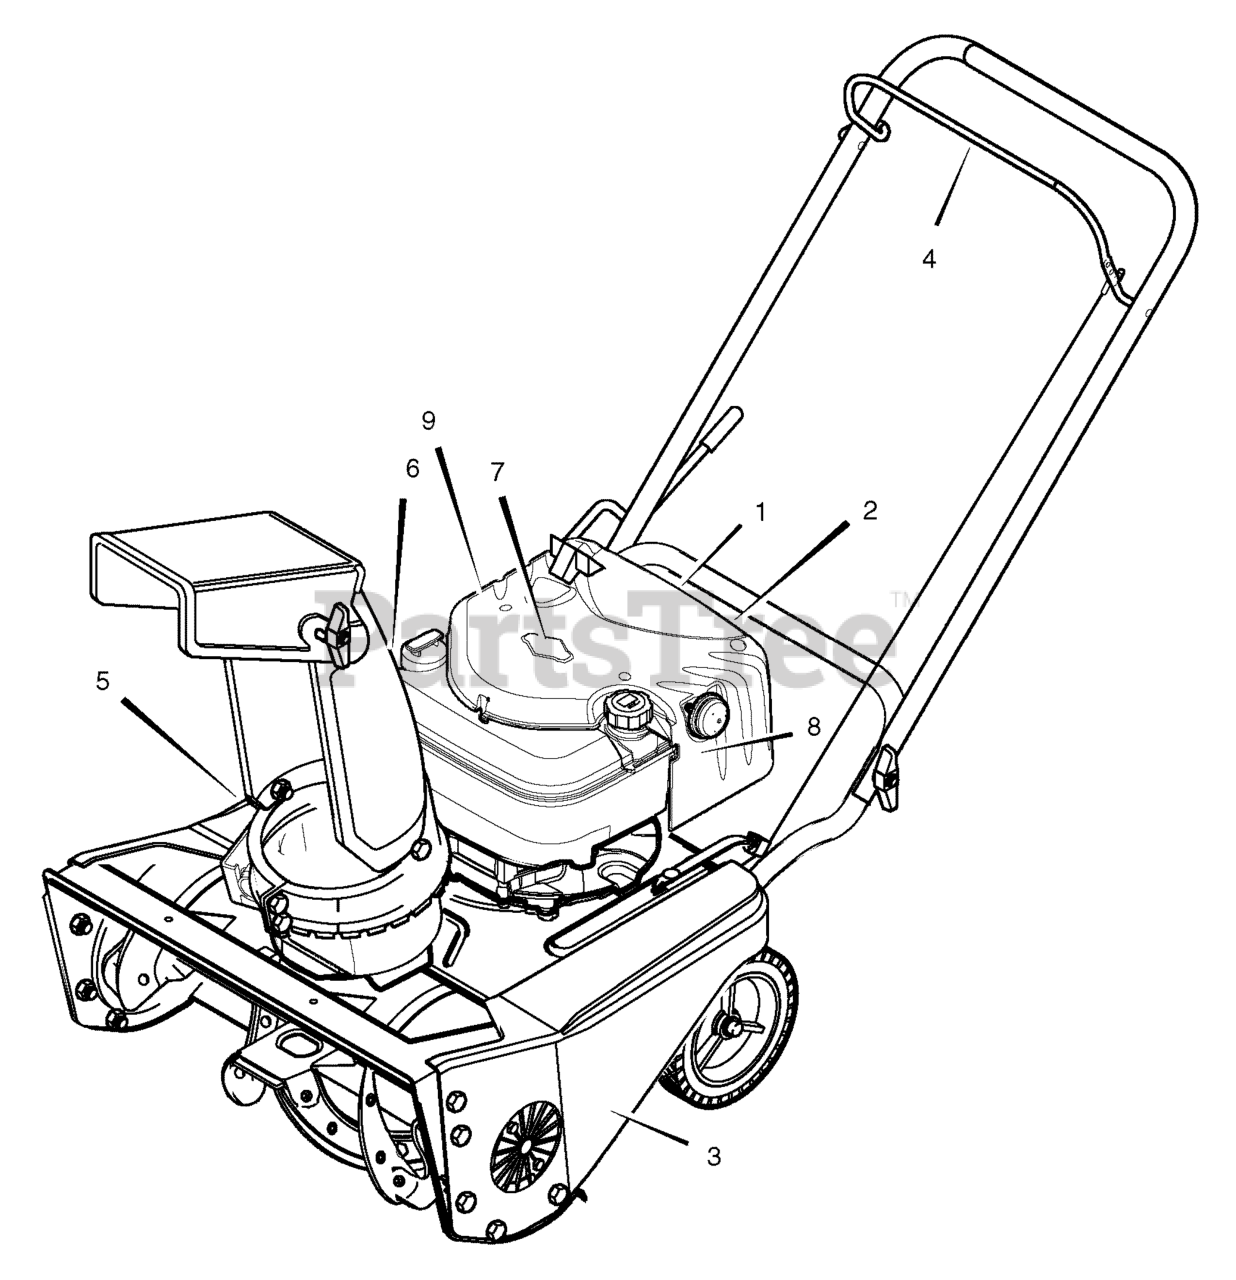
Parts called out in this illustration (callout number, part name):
1	Decal, 650/cm
2	Decal, Choke
3	Decal, Belt Instruction (inside cover)
4	Decal, Auger Control Lever
5	Decal, Danger Auger (Foot)
6	Decal, Danger Chute (Hand)
7	Decal, Briggs & Stratton
8	Decal, Primer Bulb
9	Decal, Hot Surface
